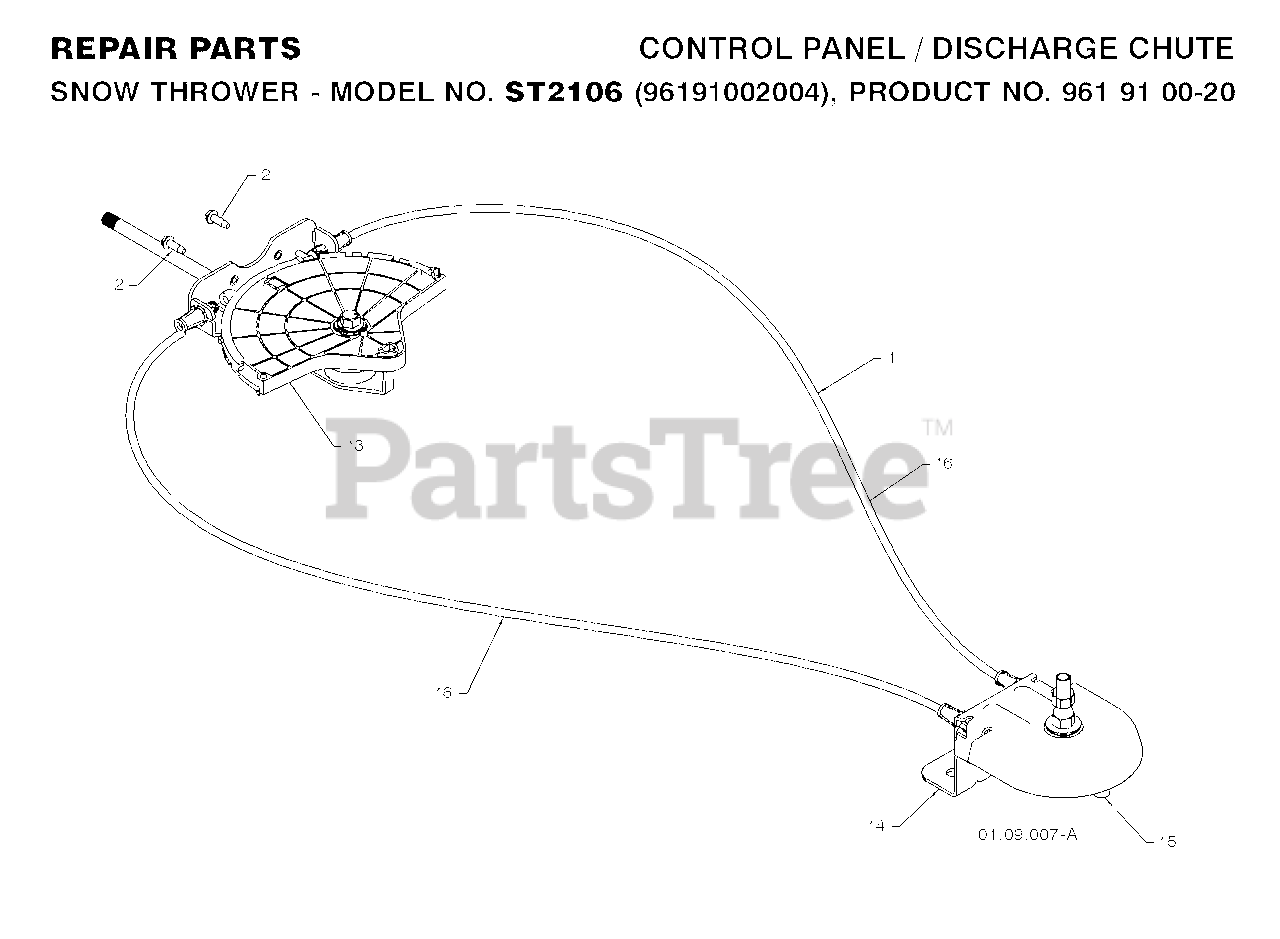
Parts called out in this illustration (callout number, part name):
1	LEVER/CABLE.ASM.ROTATOR
2	SCREW #10-24 X 5/8
3	CHUTE.ROT.HEAD.SERVICE
4	PIVOT.BRACKET
5	SNOW.PIVOT.PULLY
6	CABLE.ASSEMBLY
